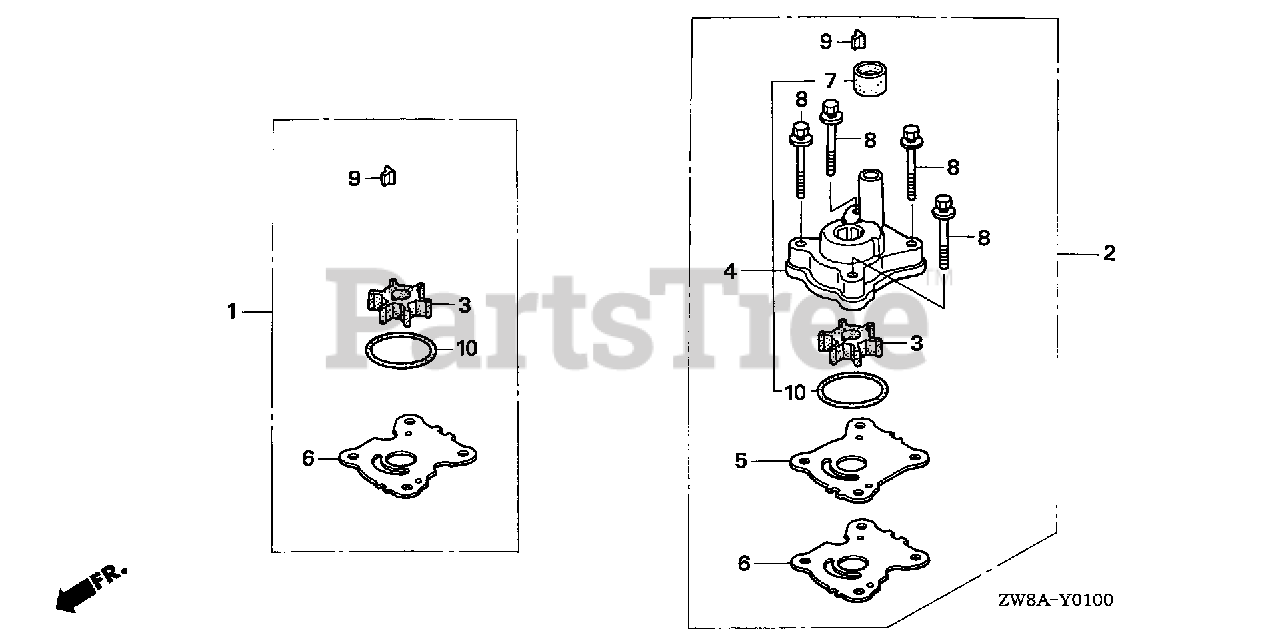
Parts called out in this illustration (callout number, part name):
1	PUMP KIT, IMPELLER
2	PUMP KIT, IMPELLER
3	IMPELLER, PUMP (UL)
4	HOUSING ASSY., IMPELLER
5	COVER, IMPELLER
6	GASKET, IMPELLER
7	RING, WATER TUBE SEAL
8	BOLT-WASHER (6X90)
9	KEY, WOODRUFF
10	O-RING (42.2X2.4)
